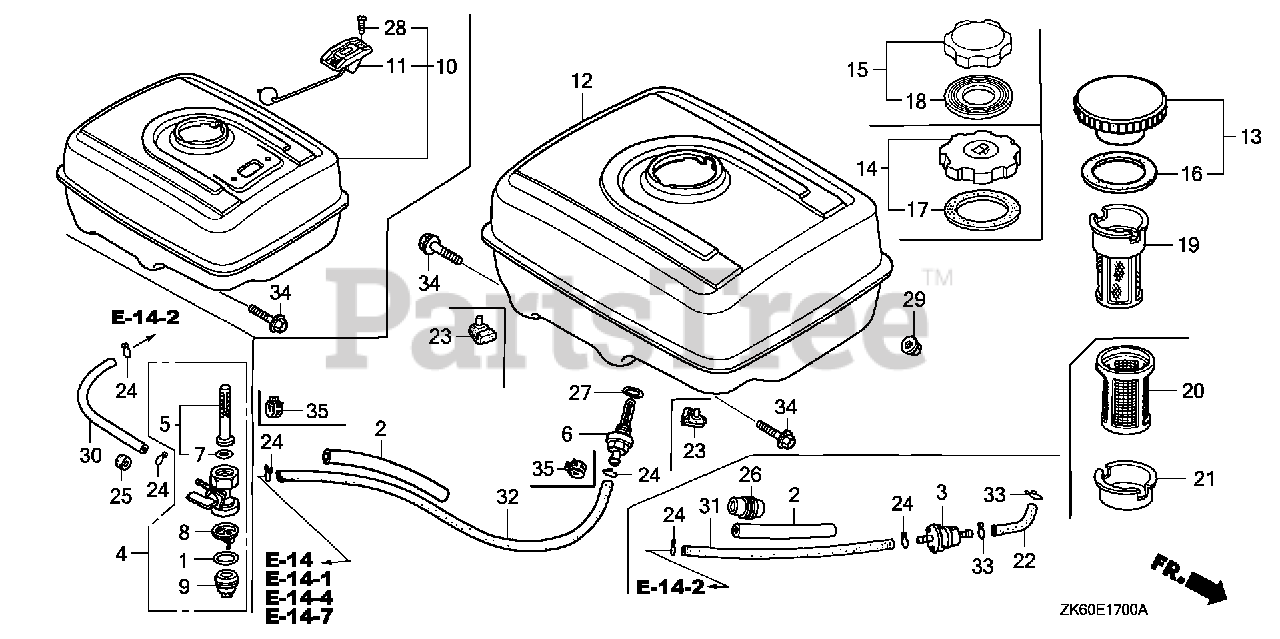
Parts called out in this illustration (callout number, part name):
2	RUBBER, SUPPORTER (107MM)
6	JOINT, FUEL TANK
12	TANK, FUEL *NH31* (MCKINLEY WHITE)
14	CAP, FUEL FILLER (BLACK)
15	CAP, FUEL FILLER (CHROME PLATED)
17	GASKET, FUEL FILLER CAP (39X58X3)
18	GASKET, FUEL FILLER CAP (39X62X3) (TOUYOUSYA)
19	FILTER, FUEL
24	CLIP, TUBE (B8)
27	O-RING (13.5X1.5) (ARAI)
27	O-RING (14MM) (NOK)
29	NUT, FLANGE (8MM)
32	BULK HOSE, FUEL (4.5X3000) (4.5X235)
34	BOLT, FLANGE (8X25)
